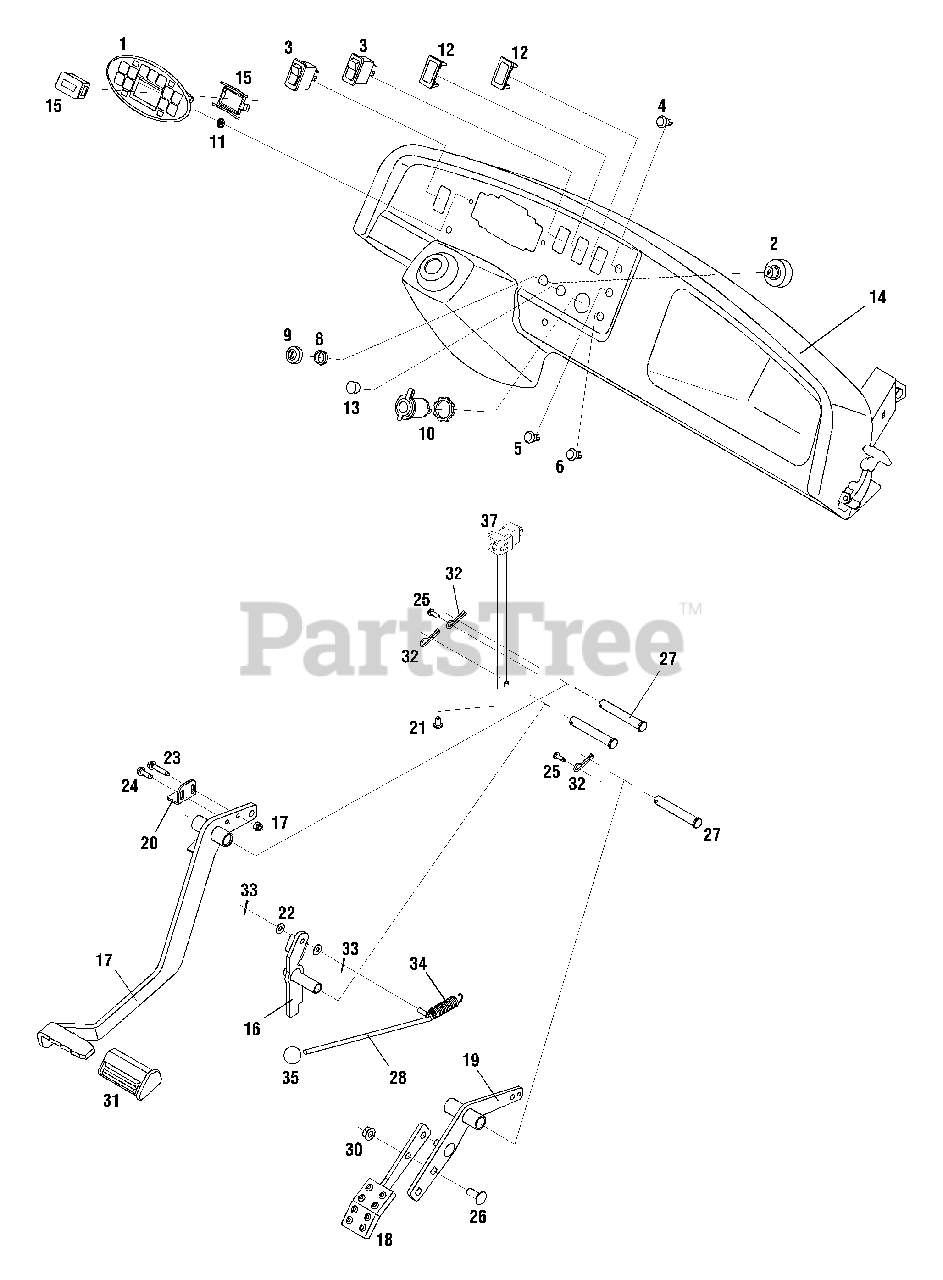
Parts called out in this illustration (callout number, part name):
1	Instrument Panel
2	Switch, Key
3	Rocker Switch
4	Switch, Green
5	Switch, Yellow
6	Switch, Red
7	Accessory Harness, Diff Lock
8	Nut, Ignition Switch, 5/8-32
9	Cap, Ignition Switch
10	Power Receptacle, 12V
11	Nut, Retainer, 1/8
13	Plug, Horn Switch
14	Dash Panel
15	Hour Meter w/ Retainer Clip
16	Lever , Parking Brake
17	Pedal Assembly, Brake
18	Pedal Assembly, Throttle
19	Pedal Arm Assembly, Throttle
20	Plate, Brake Switch
21	Screw, Hi-Lo, 1/4-20 x .5
22	Washer, Flat .25 x .630 x .0515
23	Screw, Self-Tapping, 1/4-20x1.25
24	Screw, Self-tapping, 1/4-20, .75
25	Screw, Self-tapping, #10-32 x .625
26	Bolt, Carriage, 3/8-16 x 1.0
27	Pin, Clevis .50 x 3.25
28	Rod, Brake Lock
29	Nut, Hexlock, 1/4-20 GR 8
30	Nut, Flange Lock, 3/8-16
31	Pad, Brake Pedal
32	Pin, Cotter, .125 x 1.75
33	Pin, Cotter, 1/16
34	Spring, Extension, .637 x 2.972
35	Knob, Ball
36	Cover, Protective
37	Snap Mount Switch, Interlock
